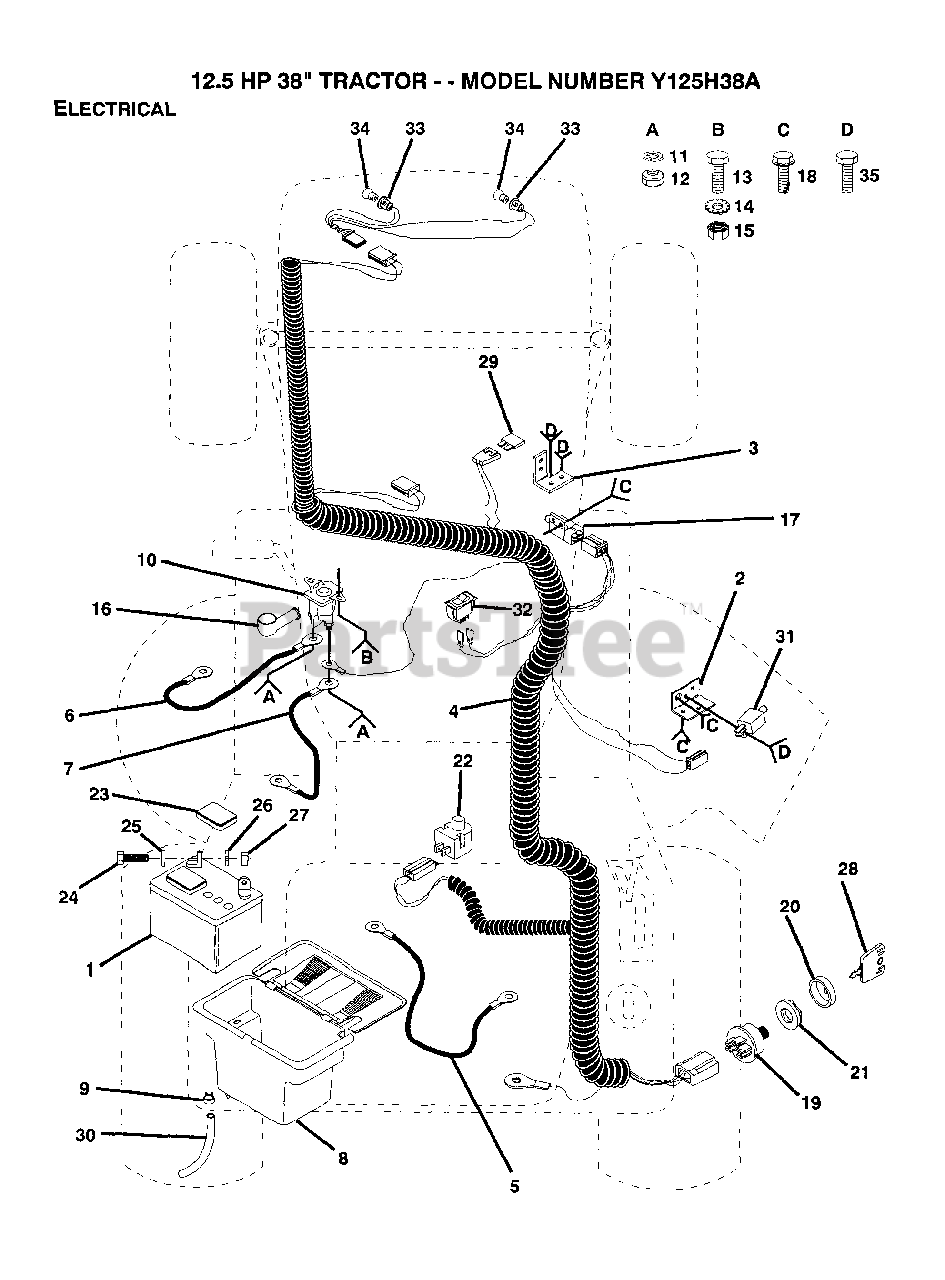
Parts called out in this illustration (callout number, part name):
2	SWITCH BRACKET
3	BRACKET LT
4	IGN HARNESS
5	CABLE T
7	"CABLE T, BATTERY"
9	HOSE CLAMP T
12	NUT
13	BOLT
15	NUT
17	SWITCH INTERLOCKT
18	SCREW
21	NUT IGNITION
22	SWITCH SEAT
23	"CAP,BATTERY "
24	BOLT LT
25	WASHER
26	LOCKWASHER
28	KEY
29	FUSE HYT
30	TUBE T
31	SWITCH-INTER. GT
32	SWITCH LT
33	HARNESS T
35	SCREW
